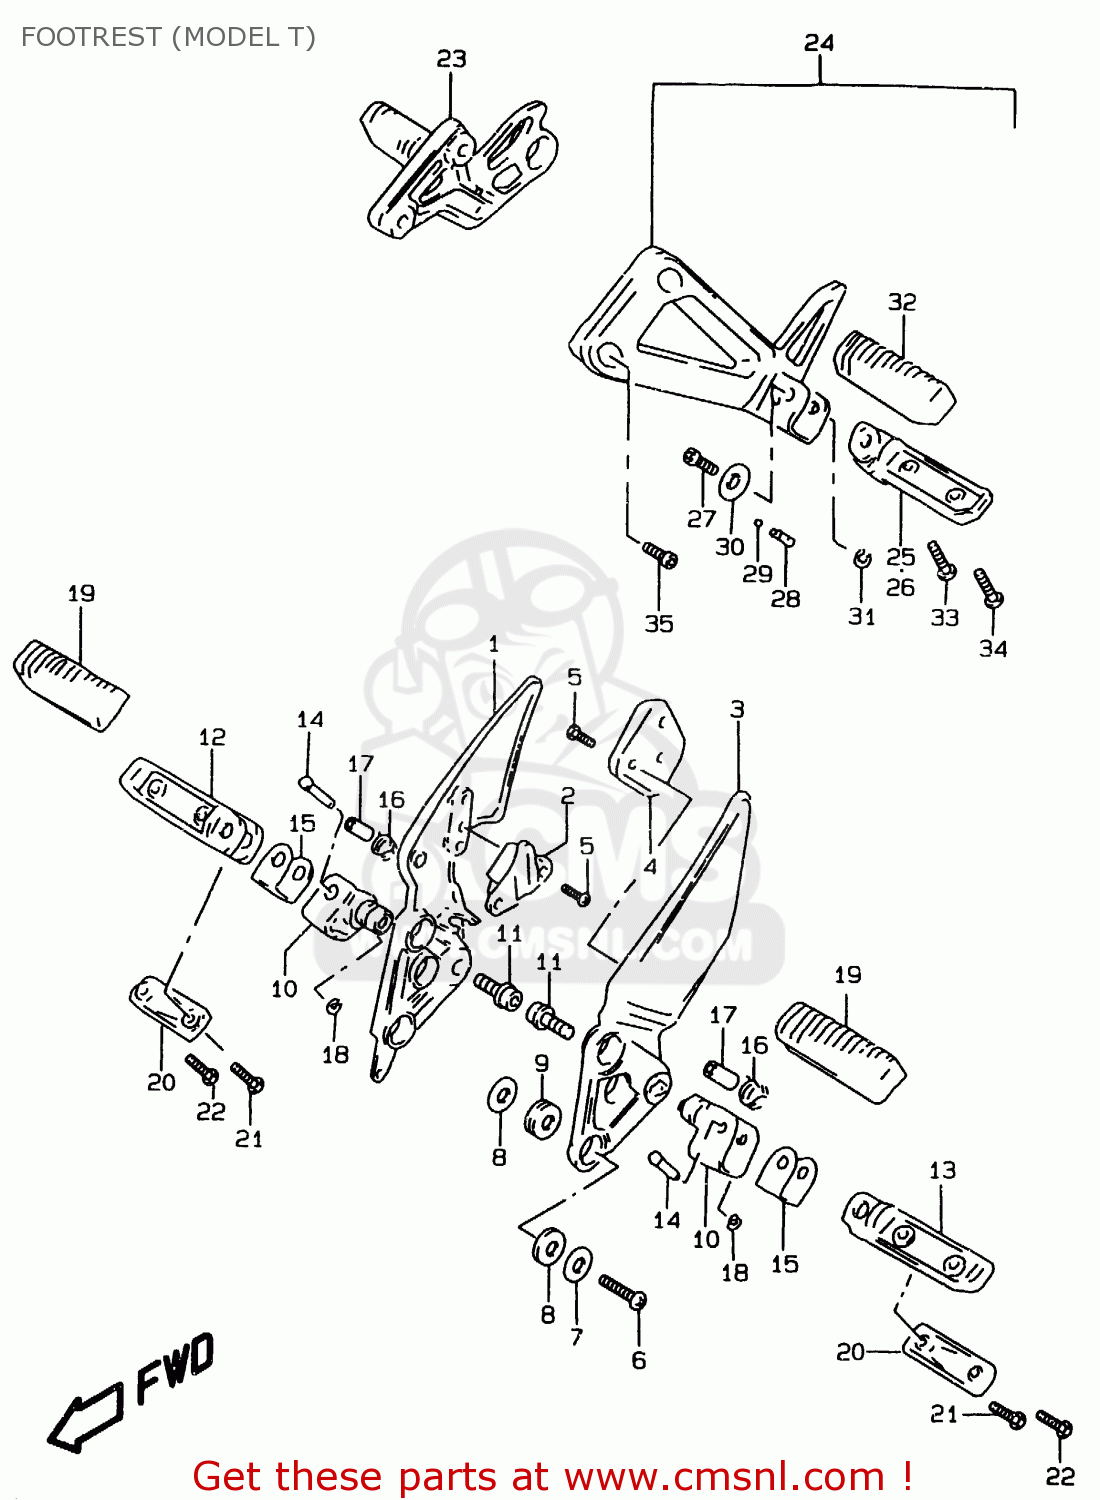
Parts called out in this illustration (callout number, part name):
1	BRACKET,FRONT FOOTREST
2	BALANCER,FOOTREST BRACKET,R
3	BRACKET,FRONT FOOTREST
4	BALANCER,FOOTREST BRACKET,L
5	SCREW
6	BOLT(8X28)
7	WASHER (8.2X24X1.6)
8	WASHER(12.6X24X1.9)
9	BUSH(12X20X16)
10	HOLDER,FOOTREST
11	BOLT(10X28)
12	BAR,FOOTREST,R
13	BAR,FOOTREST,L
14	PIN(8X33.2)
15	CUSHION,FR FOOTREST
16	SPRING
17	SPACER(8.1X12X22)
18	E.RING
19	RUBBER,FOOTREST
20	BALANCER,FR FOOTREST
21	SCREW
22	SCREW
23	FOOTREST ASSY,PILLION,R
24	FOOTREST ASSY,PILLION,L
25	BAR,PILLION FOOTREST,R
26	BAR,PILLION FOOTREST,L
27	BOLT,PILLION FOOTREST
28	SPRING
29	BALL
30	WASHER
31	E.RING
32	RUBBER,FOOTREST
33	SCREW 5X20
34	SCREW
35	BOLT(8X25)
